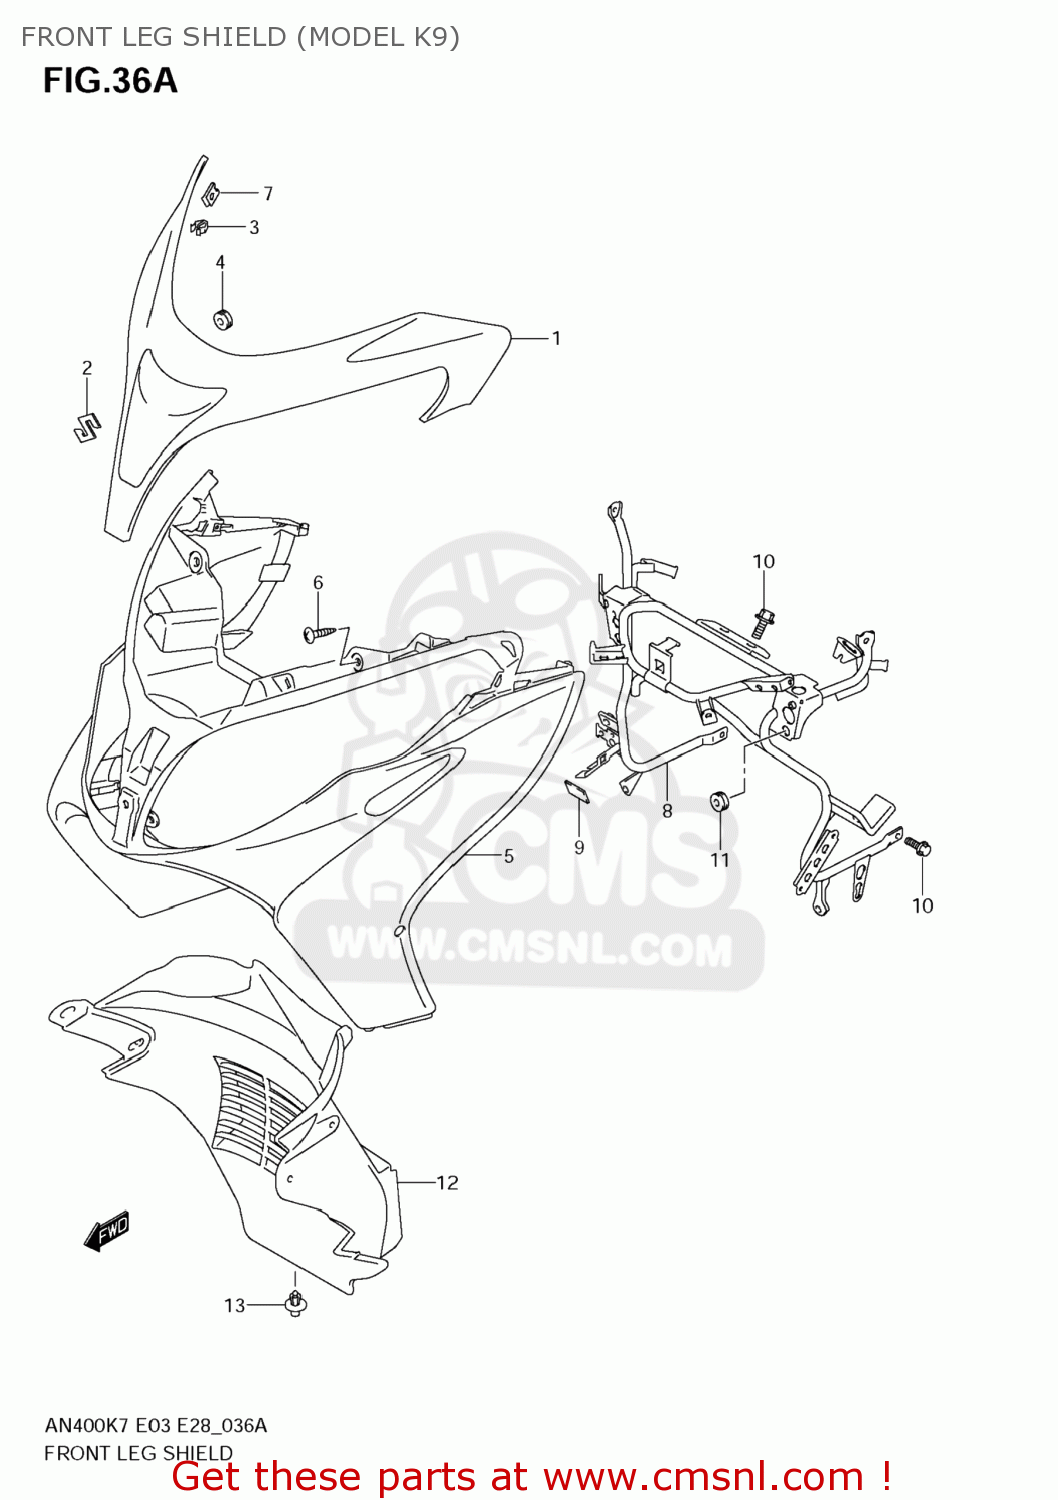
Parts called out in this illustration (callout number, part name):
1	COVER,FR LEG SHIELD(RED)
2	EMBLEM,S
3	CLIP
4	CUSHION
5	SHIELD,LEG FR
6	SCREW(6X12)
7	NUT
8	BRACE,LEG SHIELD
9	CUSHION
10	BOLT
11	CUSHION
12	SHIELD,LEG LWR
13	CLIP(BLACK)
